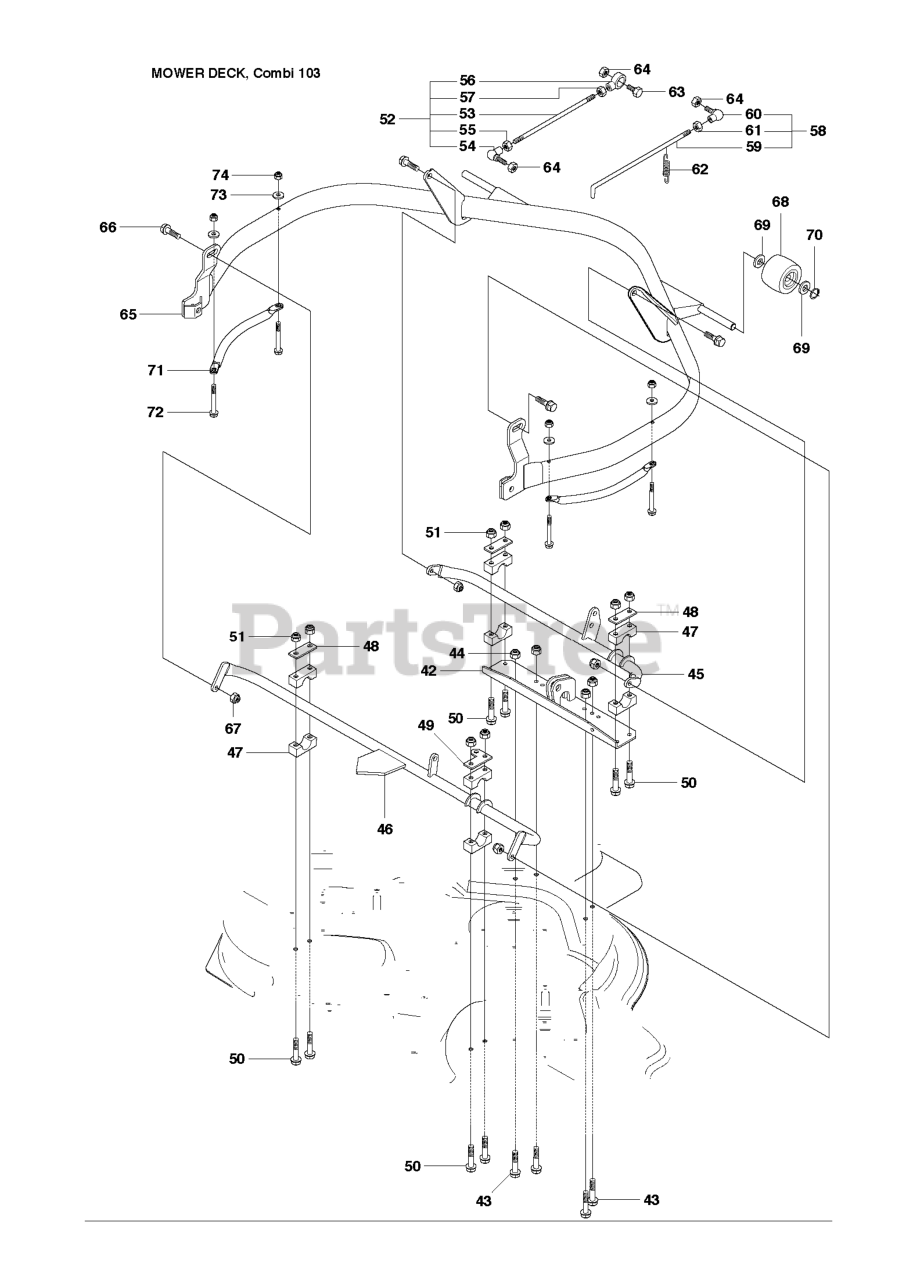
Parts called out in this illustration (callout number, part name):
44	LOCKNUT M8
51	LOCKNUT M8
52	PARALLEL RODY ASSY
57	NUT
58	CLUTCH ROD ASSY
64	NUT
65	PROTECTIVE TUBING
67	LOCKNUT M8
68	DECK ROLLER, FRONT
70	RETAINING RING SGA 15
73	WASHER
74	LOCKNUT M6
